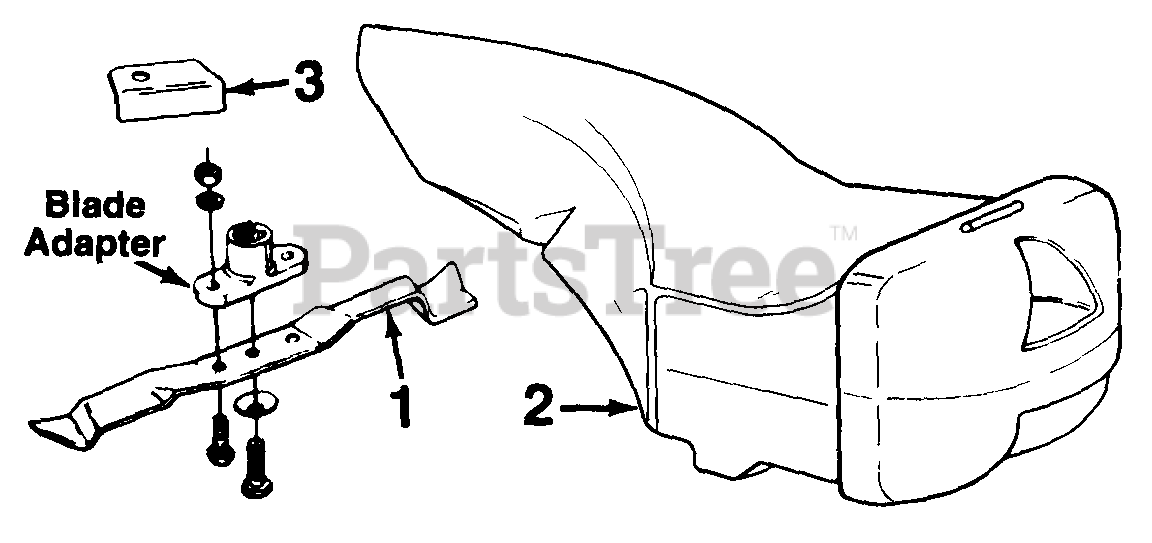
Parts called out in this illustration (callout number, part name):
1	Mulching Blade
2	Mulching Plug
3	Stop Bracket
